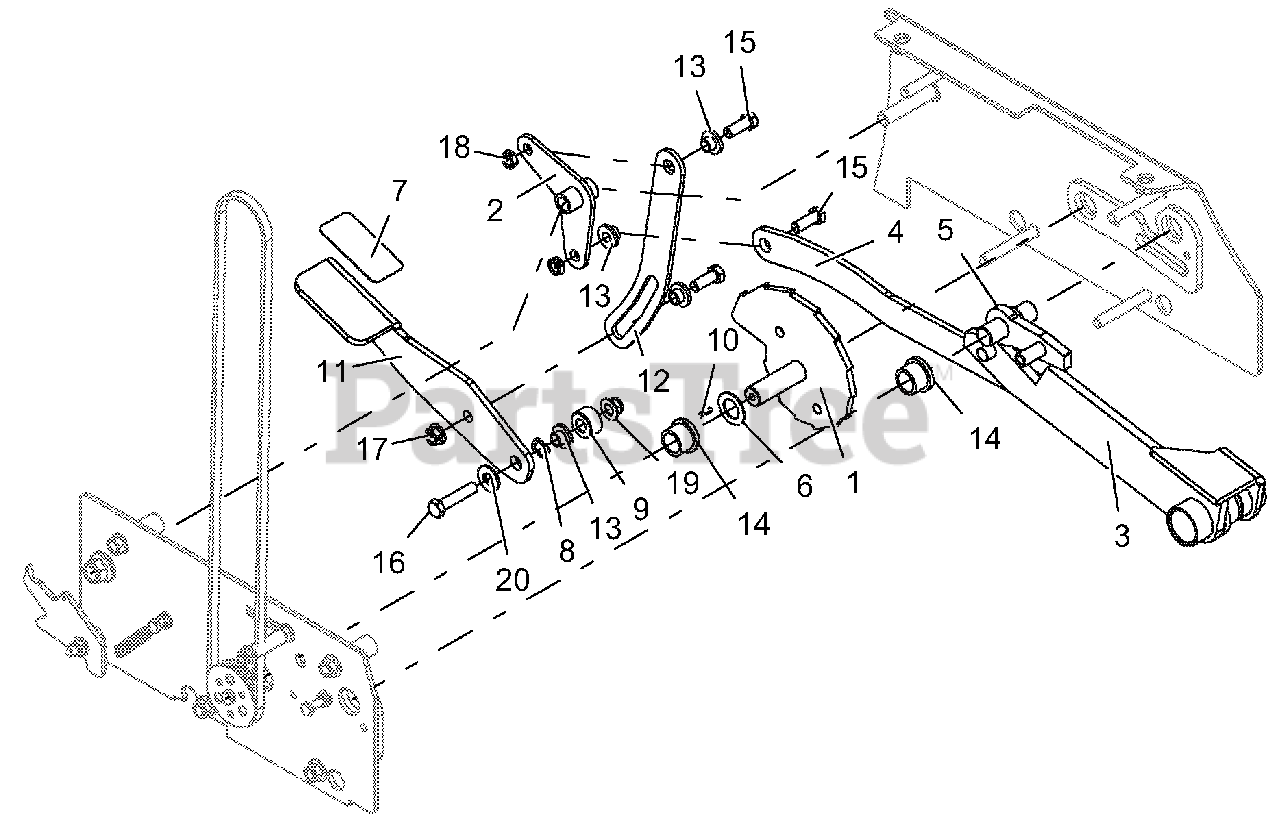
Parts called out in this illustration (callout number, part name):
1	WLDMT, HEIGHT OF CUT
2	WLDMT, REAR PIVOT-BLACK
3	WLDMT, CAM CONTACT-BLACK
4	WLDMT, DECK LIFT LINK-BLACK
5	WLDMT, TRAILER LOCK
6	BUSHING, MACH .75 X 1.25 X .048
7	GRIP, PEDAL 1.50 X 3.00
8	WAVE WASHER .531X.781X.125 FH
9	SPACER, .437X1.00X.58 SMLS
10	KEY, .125 SQ. X.50
11	PEDAL, DECK LIFT
12	ARM, PEDAL-BLACK
13	BSHG, FLG .385 X .500 X .875 X .406
14	BUSHING, .750 X 1.00 X .750
15	BLT-HEX .38-16X1.00 GR5 YWZC
16	BLT-HEX .38-16X1.75 GR5 YWZC
17	NUT, LK-CTR-FLG .38-16 YWZC
18	@NUT-LK-CTR-JAM .375-16 YWZC
19	NUT-LK-NYL-FLG .38-16 YWZC
20	WSHR-FL-STL.438X1.00X.083 YWZC
